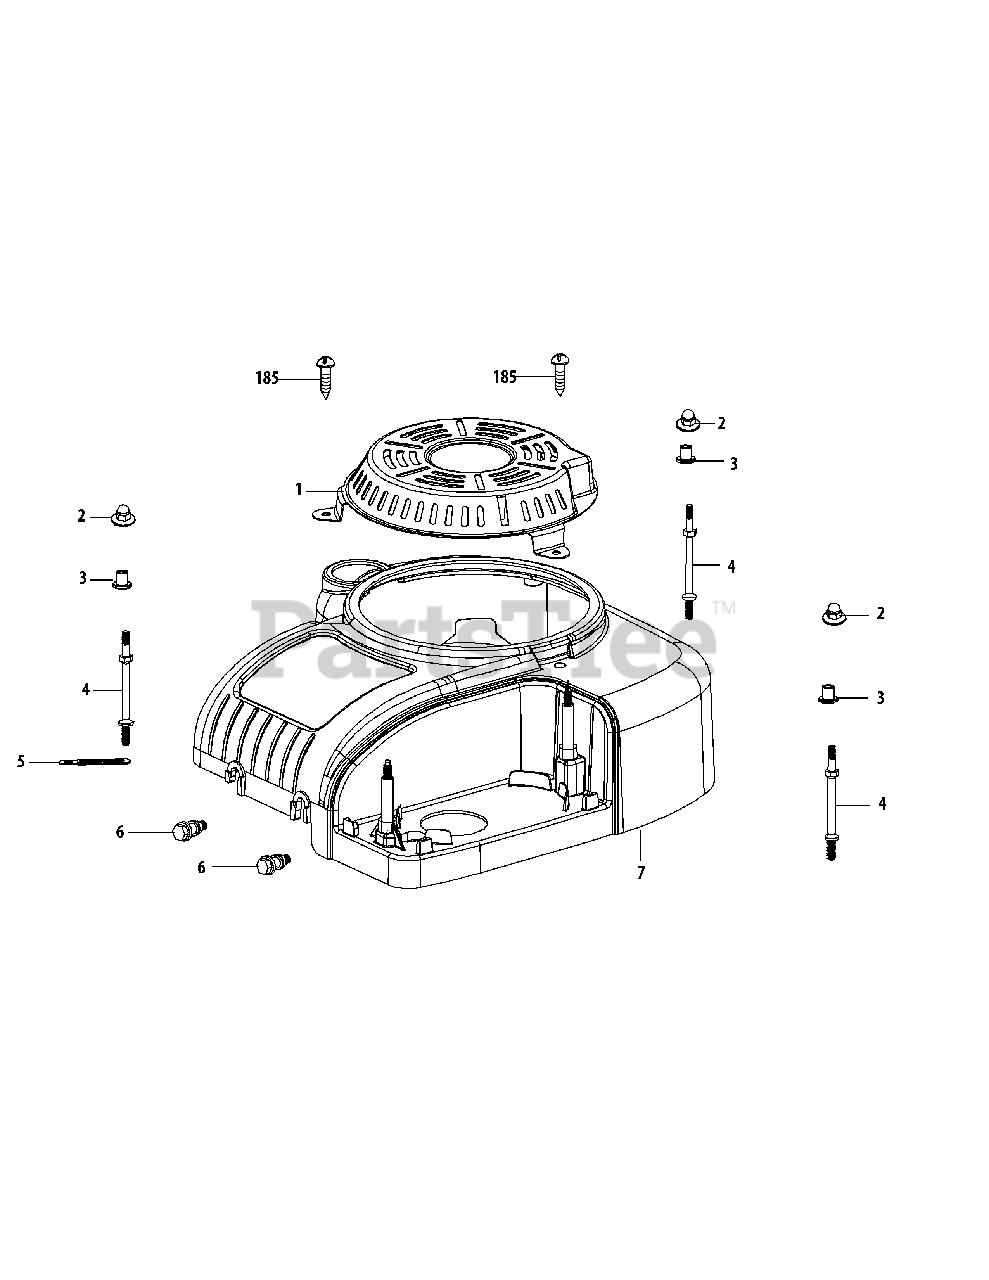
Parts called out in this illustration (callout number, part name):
1	Debris Shield
3	Engine Shroud Spacer
4	Starter / Shroud Stud M6x99
5	FLEXIBLE CLAMP
7	Air Shield
185	Self-Tapping Bolt 5.5x25
